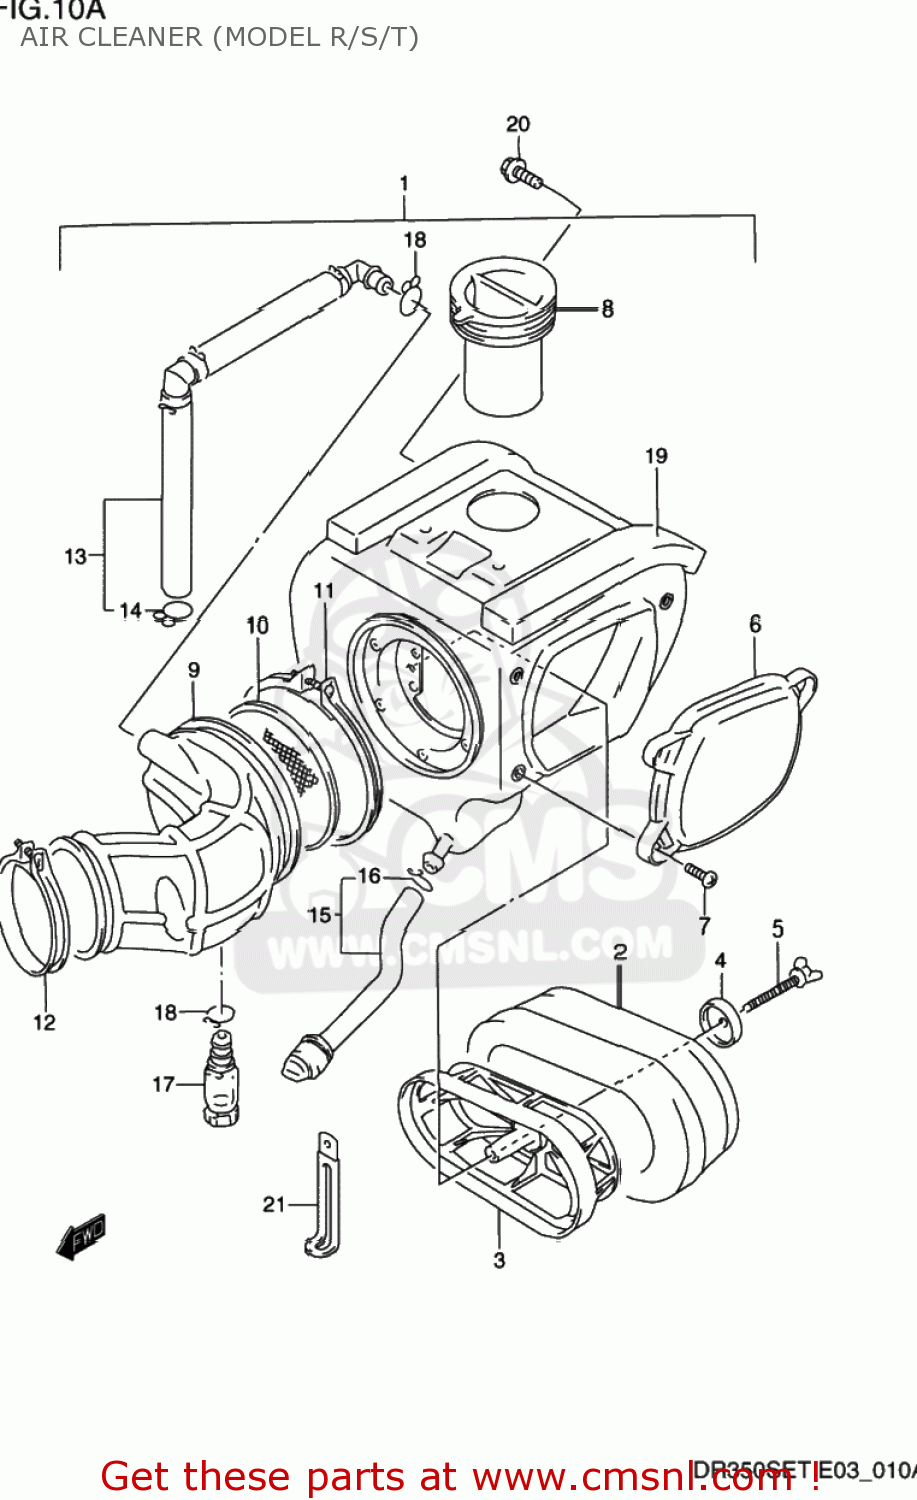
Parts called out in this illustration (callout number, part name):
1	CLEANER ASSY,AIR
2	FILTER
3	HOLDER,FILTER
4	WASHER,AIR CLEANER
5	BOLT,WING
6	CAP,AIR CLEANER
7	SCREW
8	TUBE,INLET
9	TUBE,OUTLET
10	TRAP,FRAME
11	CLAMP,OUTLET TUBE
12	CLAMP
13	TUBE,BREATHER
14	CLIP
15	TUBE,DRAIN A
16	CLIP
17	TUBE,DRAIN
18	CLIP
19	CUSHION
20	BOLT
21	CLAMP
